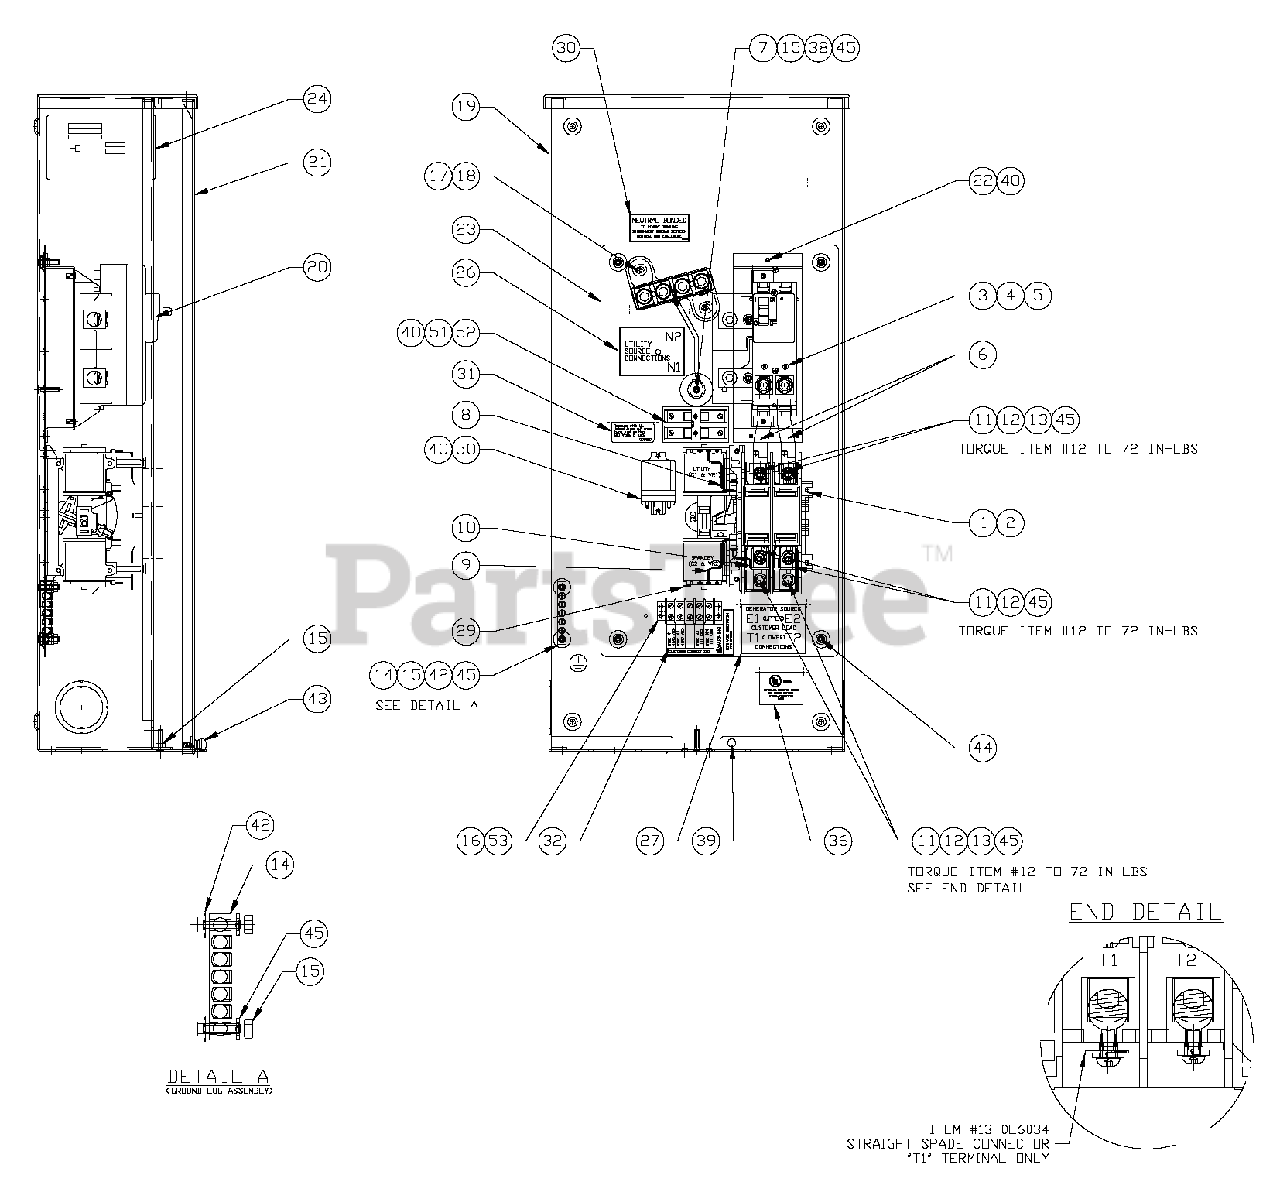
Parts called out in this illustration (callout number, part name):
1	TRANSFER SW. HSB 200A 2P 250V
2	SCREW HHTT M5-0.8 X 10 BP
3	CB 0200A 2P 240V S QN2 LL
4	BASE, QN CIRCUIT BREAKER
5	SCREW PPHM #8-32 X 1/2
6	WIRE, 3/0 N1,N2
7	WIRE, NEUTRAL BONDING 6AWG
10	WIRE-E1
11	LUG SOLDERLESS 250-#6 AL/CU
12	SCREW BHSC 1/4-20 X 3/8
13	STRAIGHT SPADE CONNECTOR
14	GROUND BAR (5) 2-14 AWG CONN
15	NUT HEX 1/4-20 SS
16	RIVET, POP .156 X .67
17	ASSY-NEUT BLK 200-400A W/TAP
18	SCREW HHTT M6-1.0 X 12 MM
19	ENCLOSURE, 200A SE XFER SW
20	COVER, INSIDE 200A DUAL BREAKER
21	COVER, TRANSFER SWITCH
22	CB BRKT 200A TRANSFER SWITCH SIEM
23	SUBPLATE, 200A SE XFER SW
24	DECAL, TRANSFER SWITCH DATA
26	DECAL, UTILITY SOURCE CONNECTION
27	DECAL, GENERATOR/ CUSTOMER CONN
29	DECAL, TRANSFER SWITCH INFO
30	DECAL, NEUTRAL CONNECTION
31	DECAL, FUSE REPLACEMENT
32	DECAL, TERMINAL STRIP
36	DECAL, UL LIST HSB
38	SCREW HHTT #8-32 X 1/4 CZ
39	NUT TRIC 1/4-20 X .525
40	SCREW HHTT M4-0.7 X 10 BP
42	WASHER SHAKEPROOF EXT 1/4 STL
43	THUMB SCREW 1/4-20x1/2
44	NUT HEX FL WHIZ 1/4-20
45	WASHER LOCK M6-1/4
50	RELAY PNL 12VDC DPDT
51	FUSEBLOCK 30A 600V 2 POLE
52	FUSE 5A X BUSS HLDR73591
53	BLOCK TERM 20A 5 X 6 X 1100V
